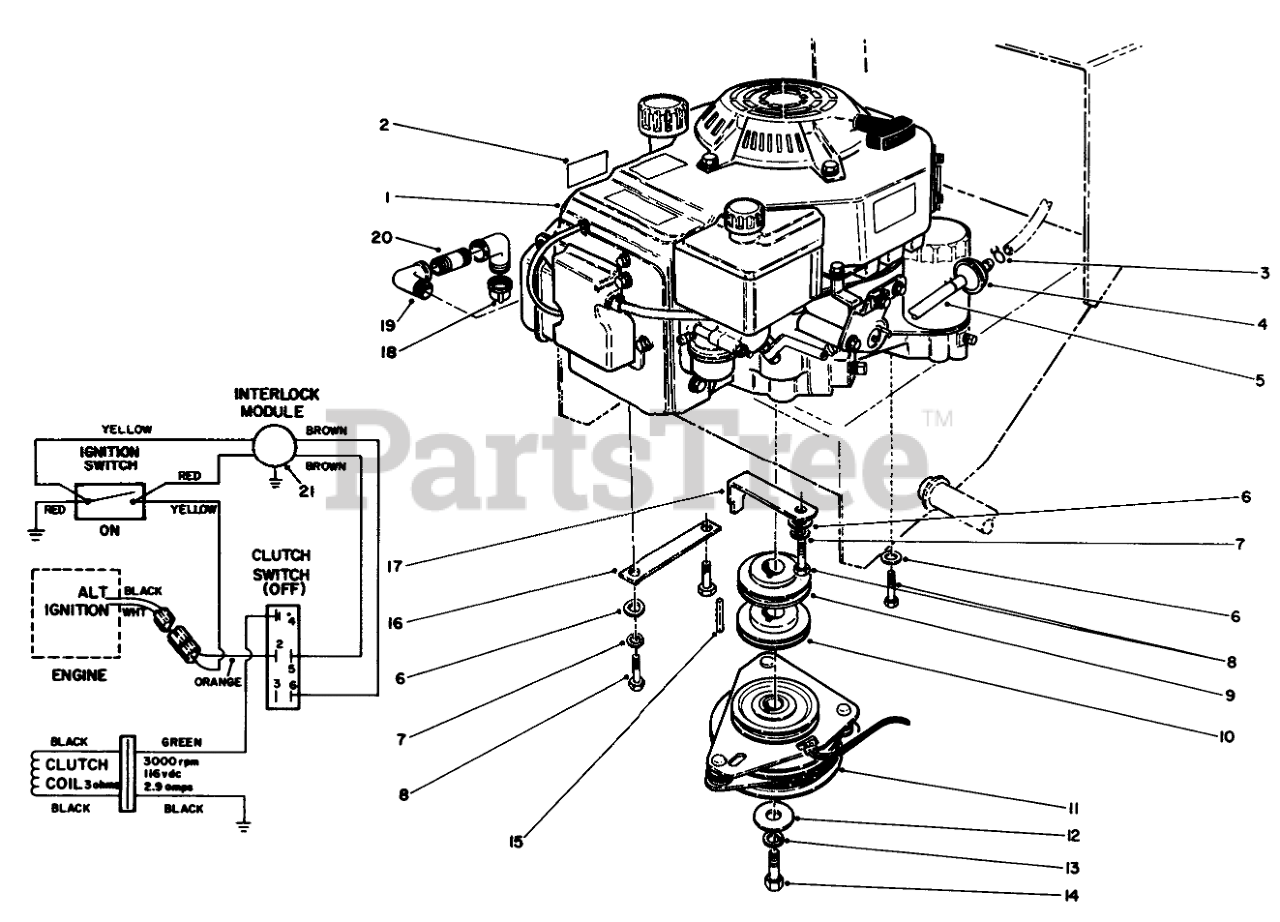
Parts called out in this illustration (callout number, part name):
2	DECAL-SURFACE, HOT
3	CLAMP-HOSE
4	FILTER-FUEL
5	HOSE-FUEL
6	WASHER-PLAIN
7	WASHER-LOCK
8	SCREW-HH
9	SHEAVE-UPPER HALF
10	SHEAVE-LOWER HALF
11	CLUTCH/BRAKE
12	WASHER-CLUTCH
13	WASHER-LOCK
14	SCREW-CLUTCH
15	KEY-SQUARE
16	Guard-Pulley
17	Retainer-Clutch
18	CAP-PIPE
19	ELBOW-STREET, 90 DEG
20	NIPPLE
21	Module
